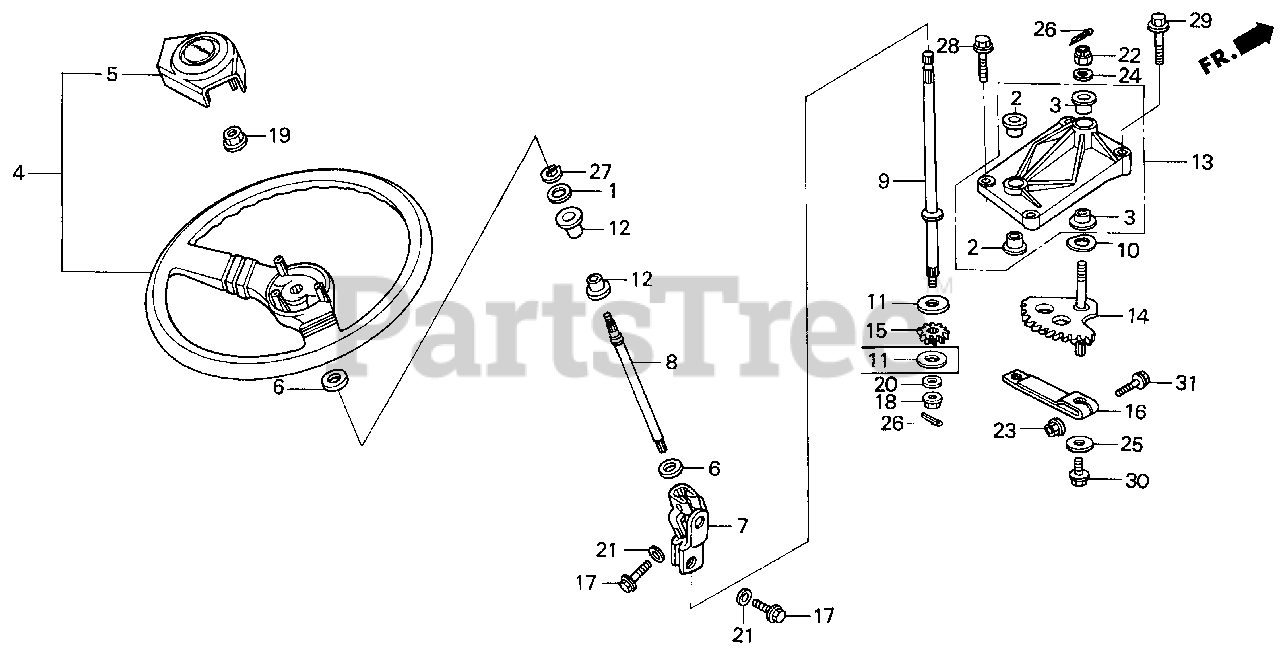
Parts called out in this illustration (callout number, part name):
1	SEAT, FR. RUBBER SPRING
2	BUSH (17X22X15)
3	BUSH (22X27X15)
4	WHEEL ASSY., STEERING
5	PAD, CENTER
6	WASHER, STEERING COLUMN
7	JOINT ASSY., STEERING
8	SHAFT A, STEERING
9	SHAFT B, STEERING
10	WASHER A, STEERING GEAR
11	WASHER (14.2X44)
12	BUSH A, STEERING SHAFT
13	CASE, STEERING GEAR
14	GEAR, STEERING DRIVEN
15	GEAR, STEERING DRIVE (9T)
16	ARM, TIE ROD
17	BOLT, STEERING YOKE (8X28) (NIPPON SEIKO)
18	NUT, SELF-LOCK (10MM) (SATO RASHI)
19	NUT, SELF-LOCK
20	WASHER (10.5X40X4)
21	WASHER, LOCK
22	NUT, CASTLE (14MM)
23	NUT, FLANGE (10MM)
24	WASHER, FLAT (14MM)
25	WASHER, PLAIN (10MM)
26	PIN, COTTER (3.0X45)
27	CIRCLIP (OUTER) (18MM)
28	BOLT, FLANGE (8X35)
29	BOLT, FLANGE (8X40)
30	BOLT, FLANGE (10X16)
31	BOLT, FLANGE (10X50)
